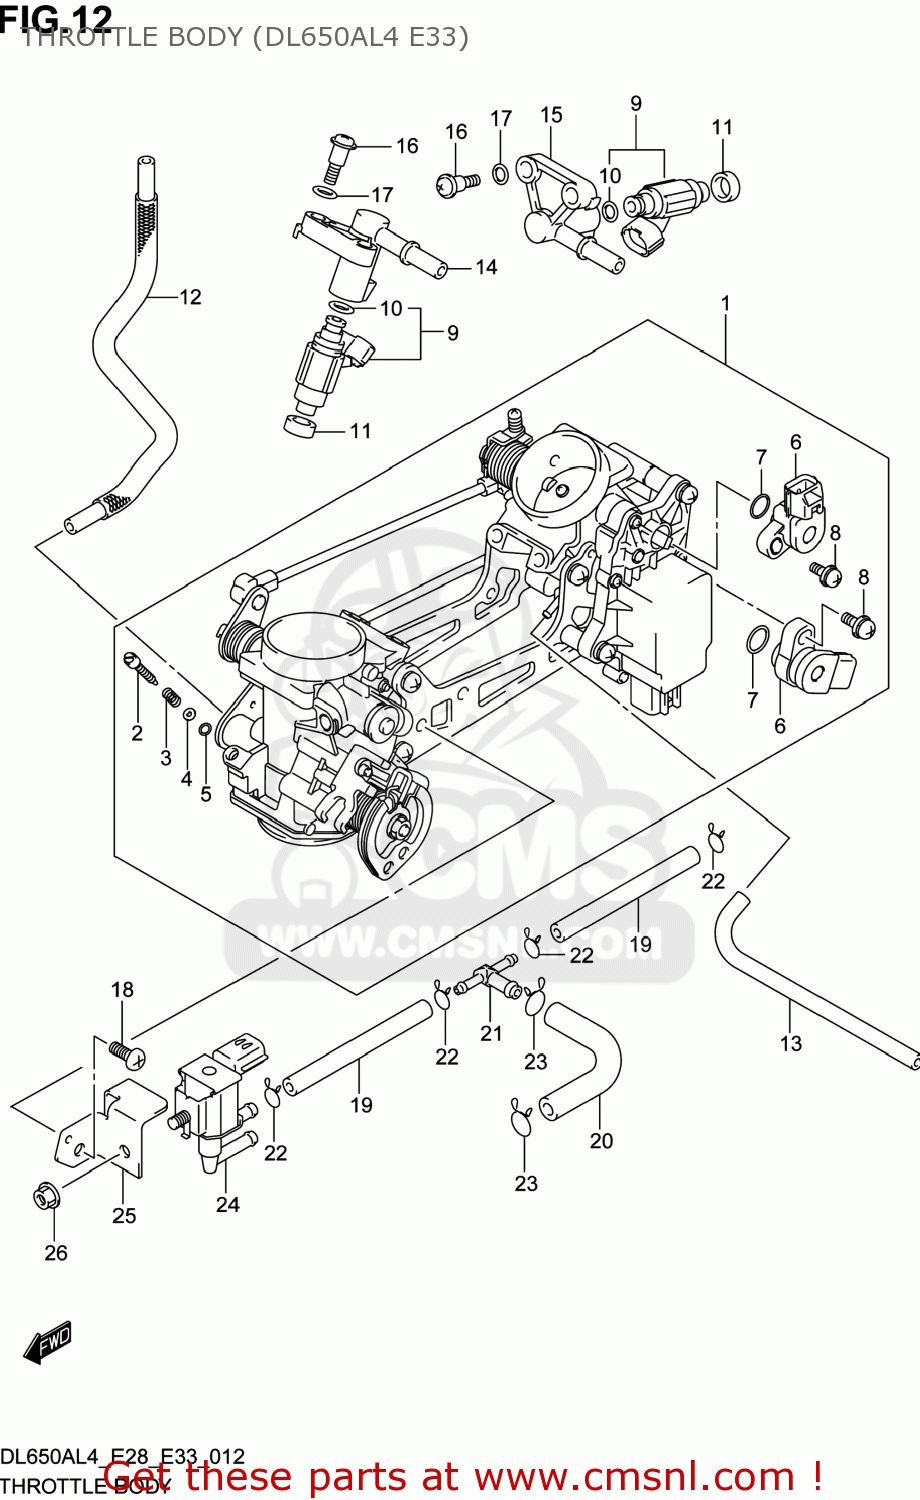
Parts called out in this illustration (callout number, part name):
1	BODY ASSY,THROTTLE
2	SCREW
3	SPRING,THROTTLE SCREW
4	WASHER
5	O RING,PILOT AIR SCREW
6	SENSOR
7	O RING
8	SCREW
9	INJECTOR ASSY
10	O-RING
11	SEAL
12	HOSE
13	HOSE
14	DELIVERY PIPE
15	DELIVERY PIPE
16	SCREW
17	PACKING (NAS)
18	SCREW
19	HOSE
20	HOSE
21	NIPPLE
22	CLIP
23	CLIP
24	VALVE,CANISTER PURGE
25	BRACKET
26	NUT
